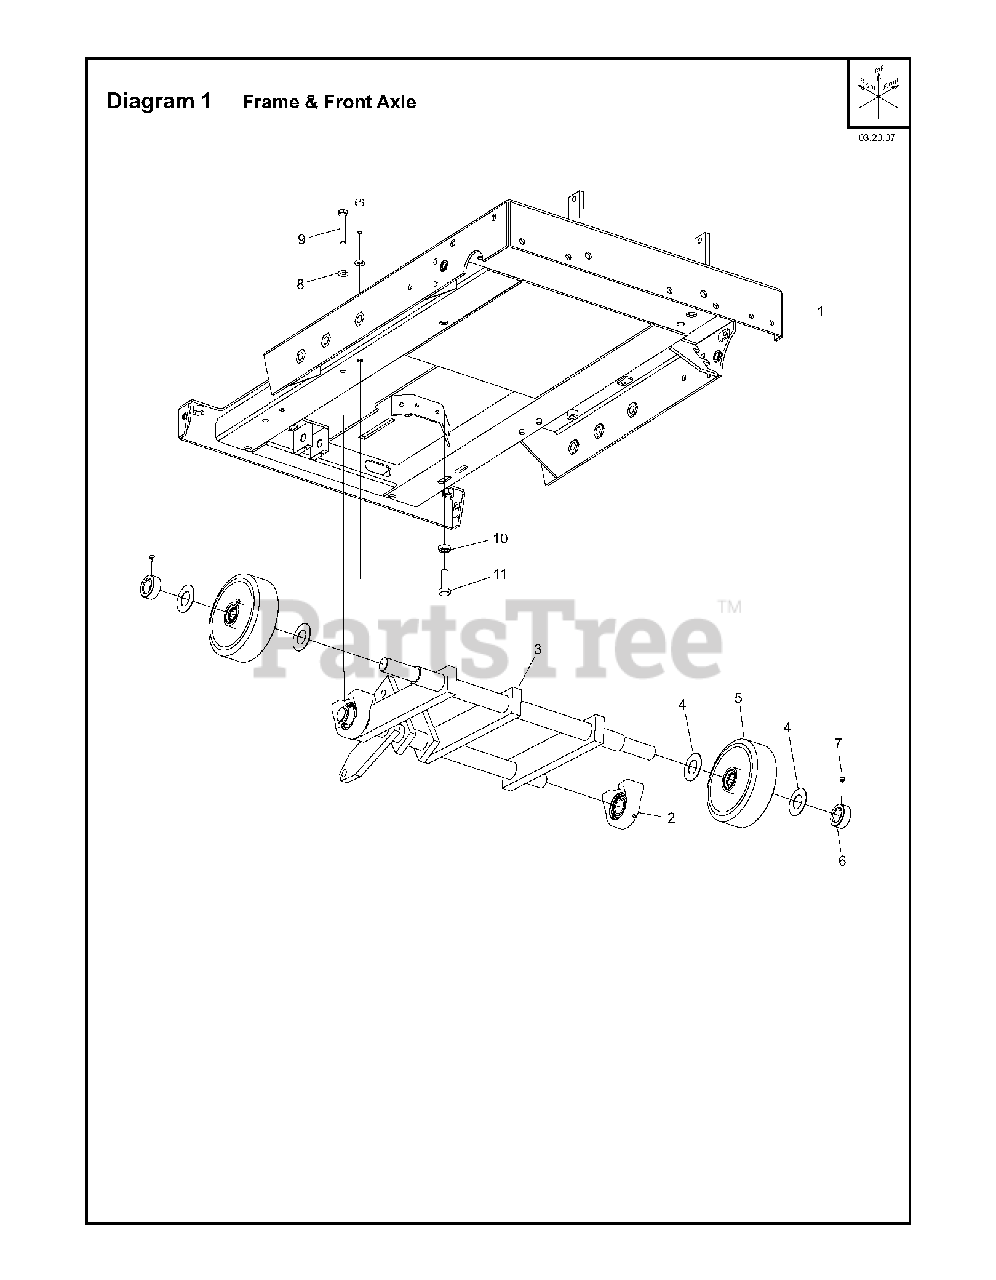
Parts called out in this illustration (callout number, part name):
2	BRG 1 PILLOWBLOCK BB
3	FRONT AXLE WLDMT
7	SHSS. .3125-18 x .25 CUP HK
8	LOCKWASHER. SPLIT .375
9	HHCS. .375-16 x 2.25 GR 5 Z/P
